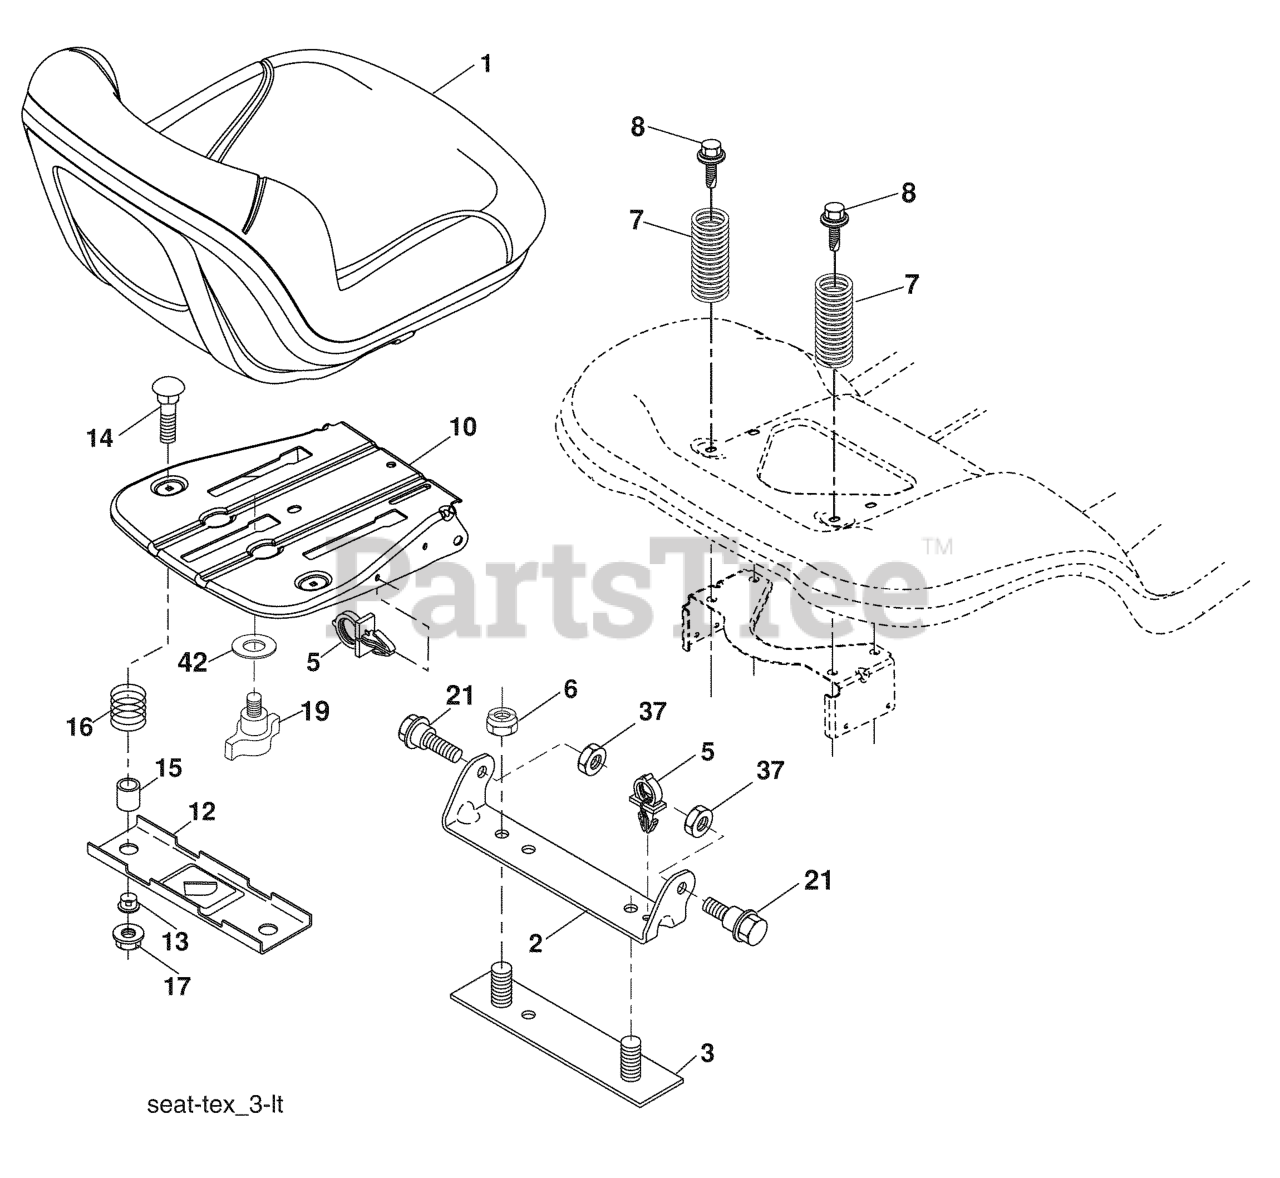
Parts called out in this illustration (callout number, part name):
1	SEAT.TH130.GRY.MILSCO.
2	BRKT.PIVOT.FENDER
3	STRAP
6	NUT
7	SPRING COMPRESSION
8	BOLT.5/16-18UNCX3/4 W/SEMS.BLK
10	PAN.ASM.SEAT.SHORT
12	BRKT.MNT.OPC.SW.SEAT.
14	BOLT.ROUND.HEAD.SQUARE.NECK
15	SPACER SPLIT 28X.96
16	SPRING COMPRESSED
17	NUT T
19	KNOB.SEAT.ADJ.
21	BOLT.SHOULDER.5/16-18
37	NUT.71038.31-18.HEX.NYLOCK
42	WASHER.CUP.SEAT.
